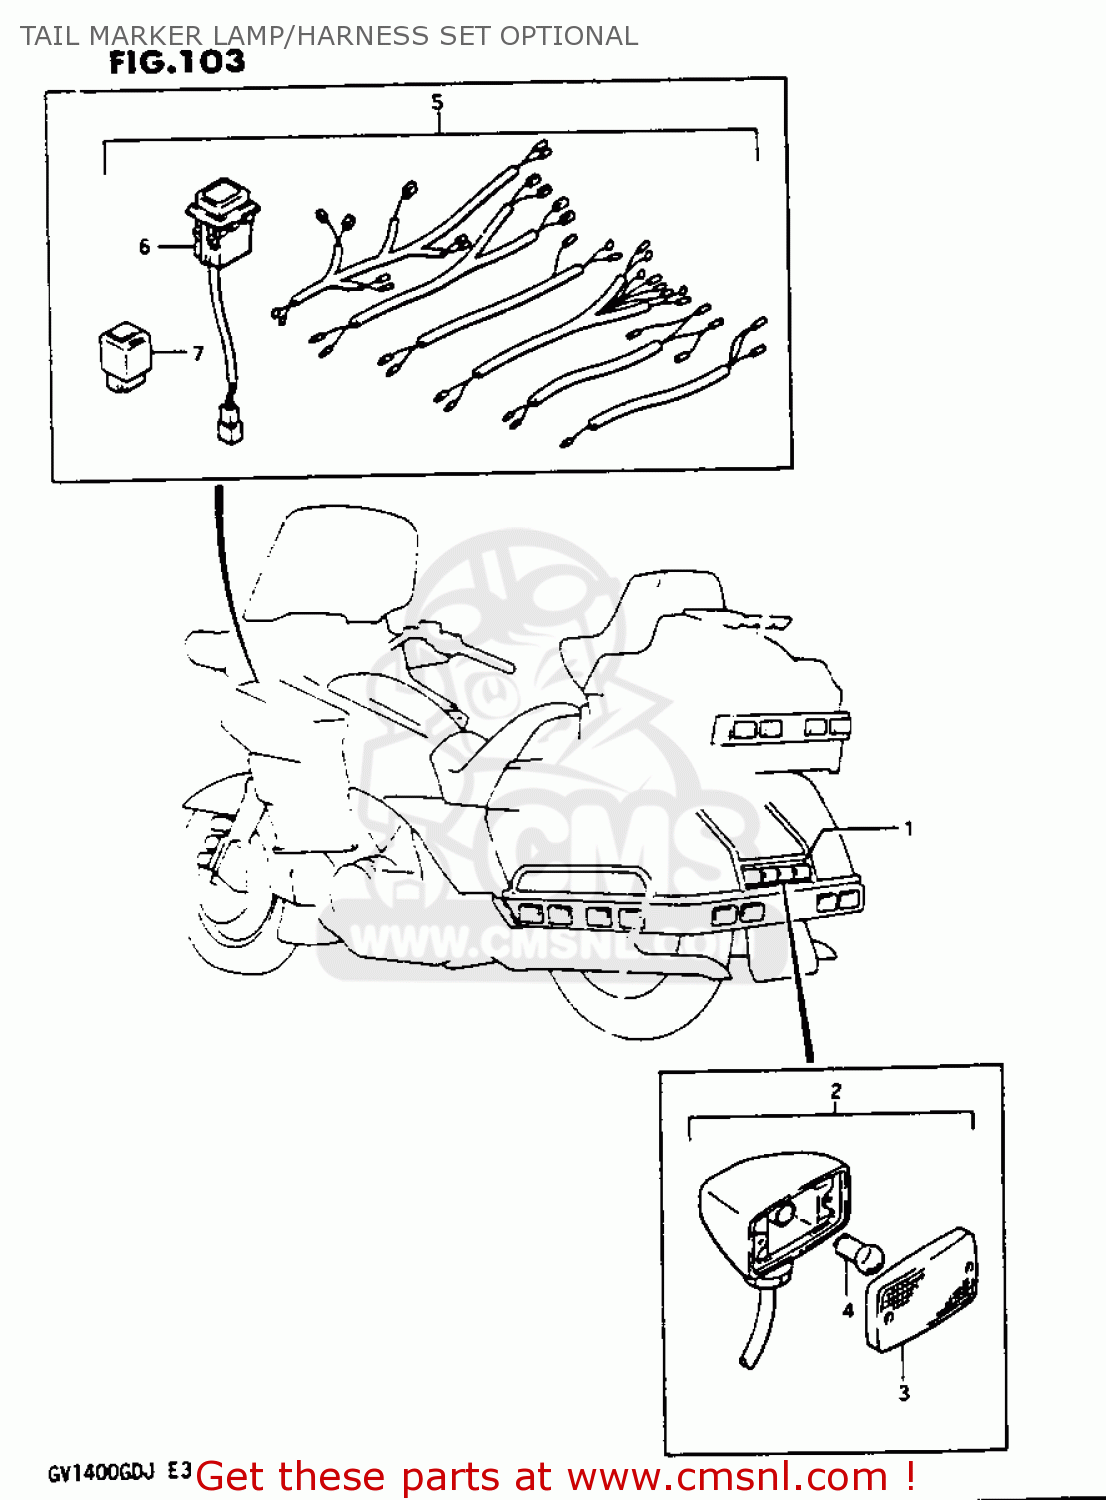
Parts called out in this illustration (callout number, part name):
1	REAR END,MARKER LAMP S
2	TRAVEL TRUNK,MARKER LAMP
3	LENS
4	BULB 12V 3W
5	MARKER LAMP SWITCH & WASHER
6	SWITCH ASSEMBLY,MARKER LAMP
7	RELAY ASSY, MARKER LAMP
